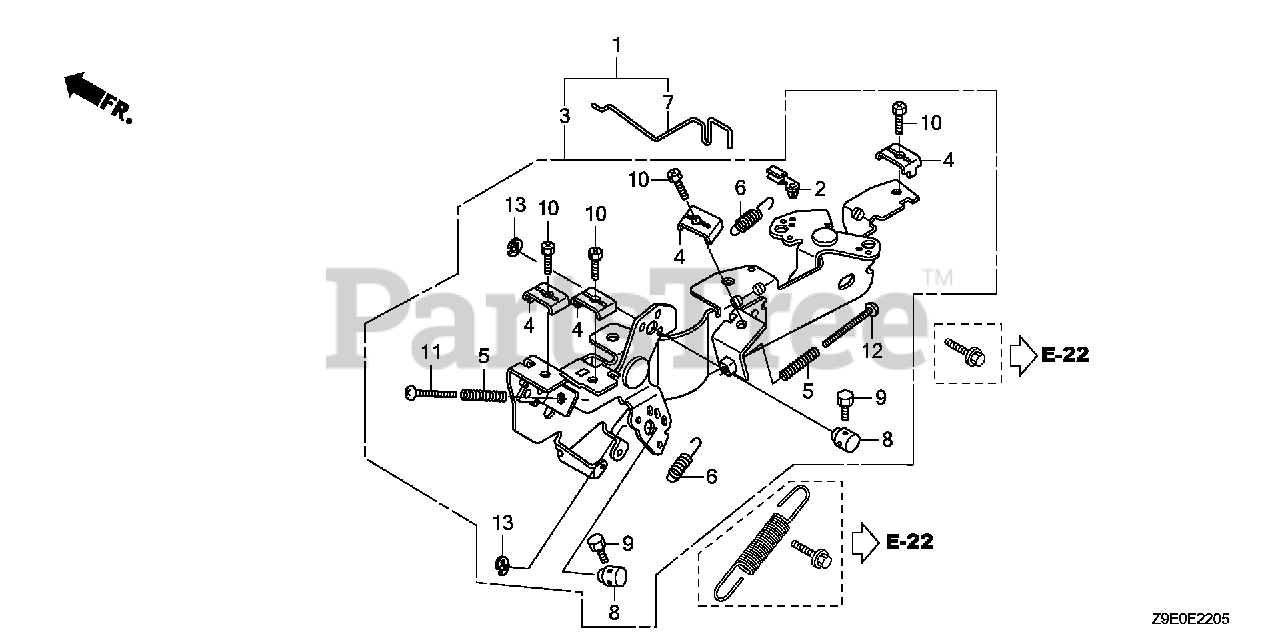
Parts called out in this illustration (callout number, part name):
1	CONTROL KIT
2	JOINT, ROD
3	CONTROL ASSY.
4	HOLDER, CABLE
5	SPRING, CONTROL ADJUSTING Use from Engine SN 2327377.
6	SPRING, CABLE RETURN
7	ROD, CHOKE CONTROL
8	HOLDER, CABLE
9	BOLT, RECESSED (4X6)
10	BOLT, RECESSED (5X16)
11	SCREW, PAN (5X30)
12	SCREW, PAN (5X45)
13	E-RING (5MM)
